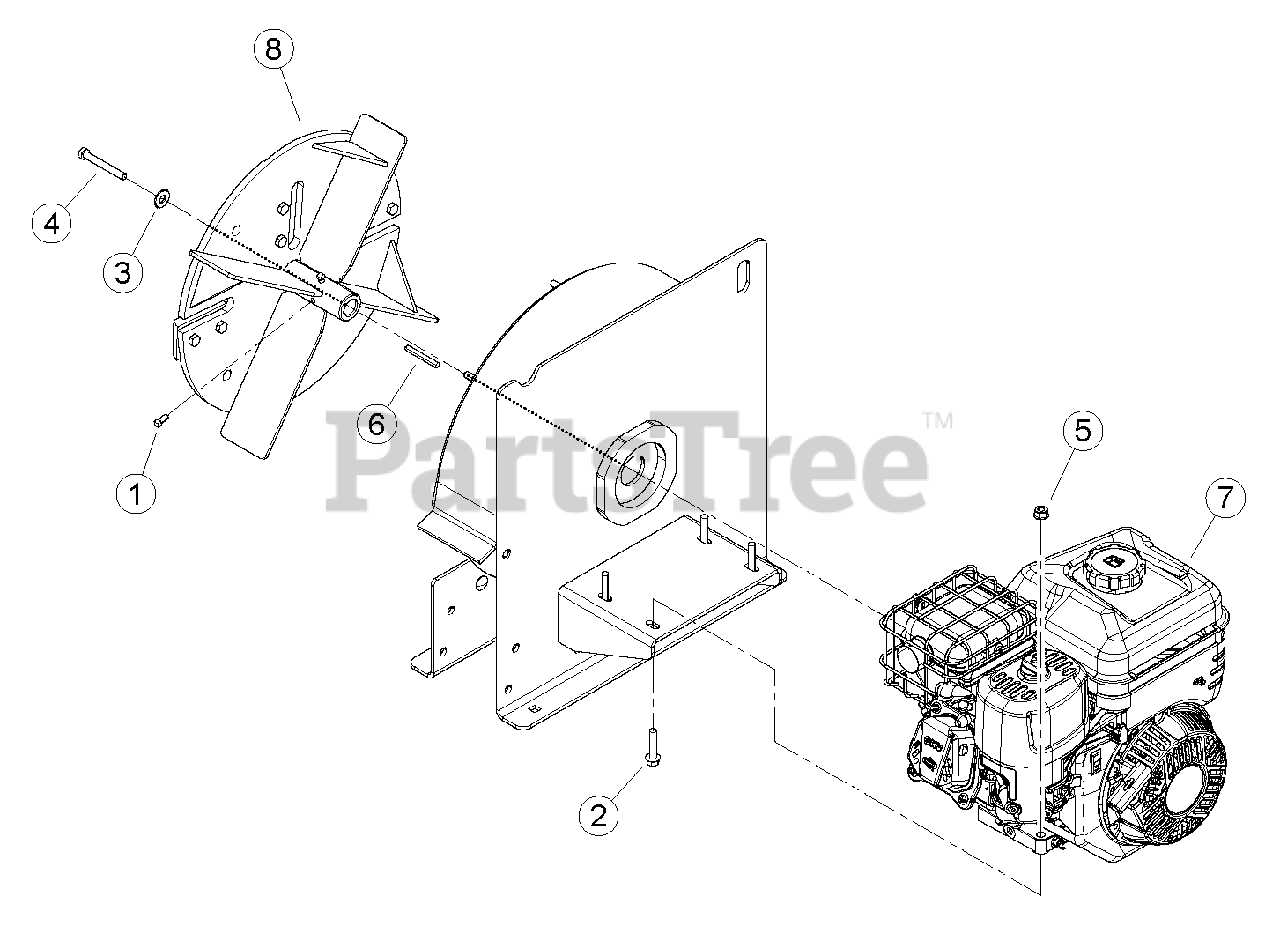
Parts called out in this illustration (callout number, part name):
1	SCREW, 1/4" X 1/2" SQ HD CP SET
2	BOLT, 5/16 X 1-1/2 FLANGE NC
3	WASHER, 5/16 GR8 USS FLAT
4	BOLT, 5/16 X 2-1/2" NF GR5 ZP HHCS
5	NUT, 5/16-18 NYLOCK FLANGE
6	KEY, 3/16 SQ X 2" PLAIN
7	ENGINE, 208CC 900 SERIES B&S (FOR SERVICE SEE ENGINE OWNER'S MANUAL OR NEAREST BRIGGS & STRATTON INDUSTRIAL ENGINE DEALER)
8	ASSEMBLY, FC ROTOR KNIVES
